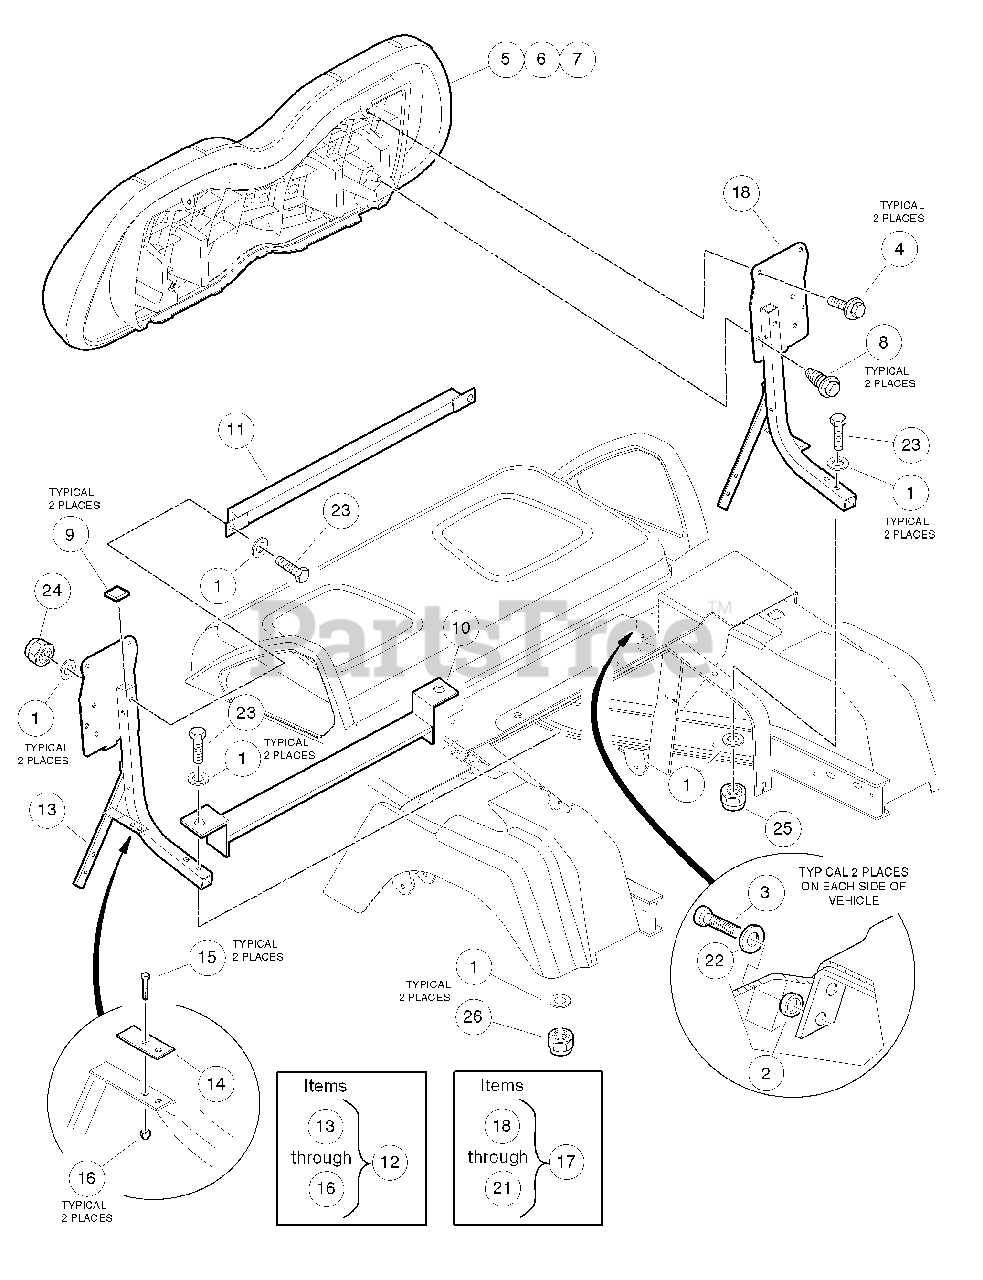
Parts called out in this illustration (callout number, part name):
1	Washer, 1/4 Flat
2	Body Spacer
3	Screw, 5/16-18 X 1.25 Thrd Frm
4	Screw - M6 X 1.0 X 30 Sems
5	Service Backrest Asm, Beige
6	Service Backrest Asm, White
7	Service Backrest Asm, Gray
8	Screw, M6 Hex
9	Plug, Square - 25.4 mm
10	Weldment, Bed Support
11	Seat Support, Cross Brace
12	Seat Support W/striker, Drv
13	Seat Support, Driver-Side
14	Striker Plate
15	Screw, 1/4-20 X 0.75 Hex-Head Cap
16	Locknut, 1/4-20 Nylon Insert
17	Support, Seat, Right
18	Seat Support, Passenger-Side
19	Striker Plate
20	Screw, 1/4-20 X 0.75 Hex-Head Cap
21	Locknut, 1/4-20 Nylon Insert
22	Washer, 5/16 Type A Flat
23	Screw, 1/4-20 X 2.00 Hex-Head Cap
24	Locknut, 5/16-18 Nylon Insert
25	Locknut, 1/4-20 Nylon Insert
26	Screw, 5/16-18 X 1.75 Hex-Head Cap
